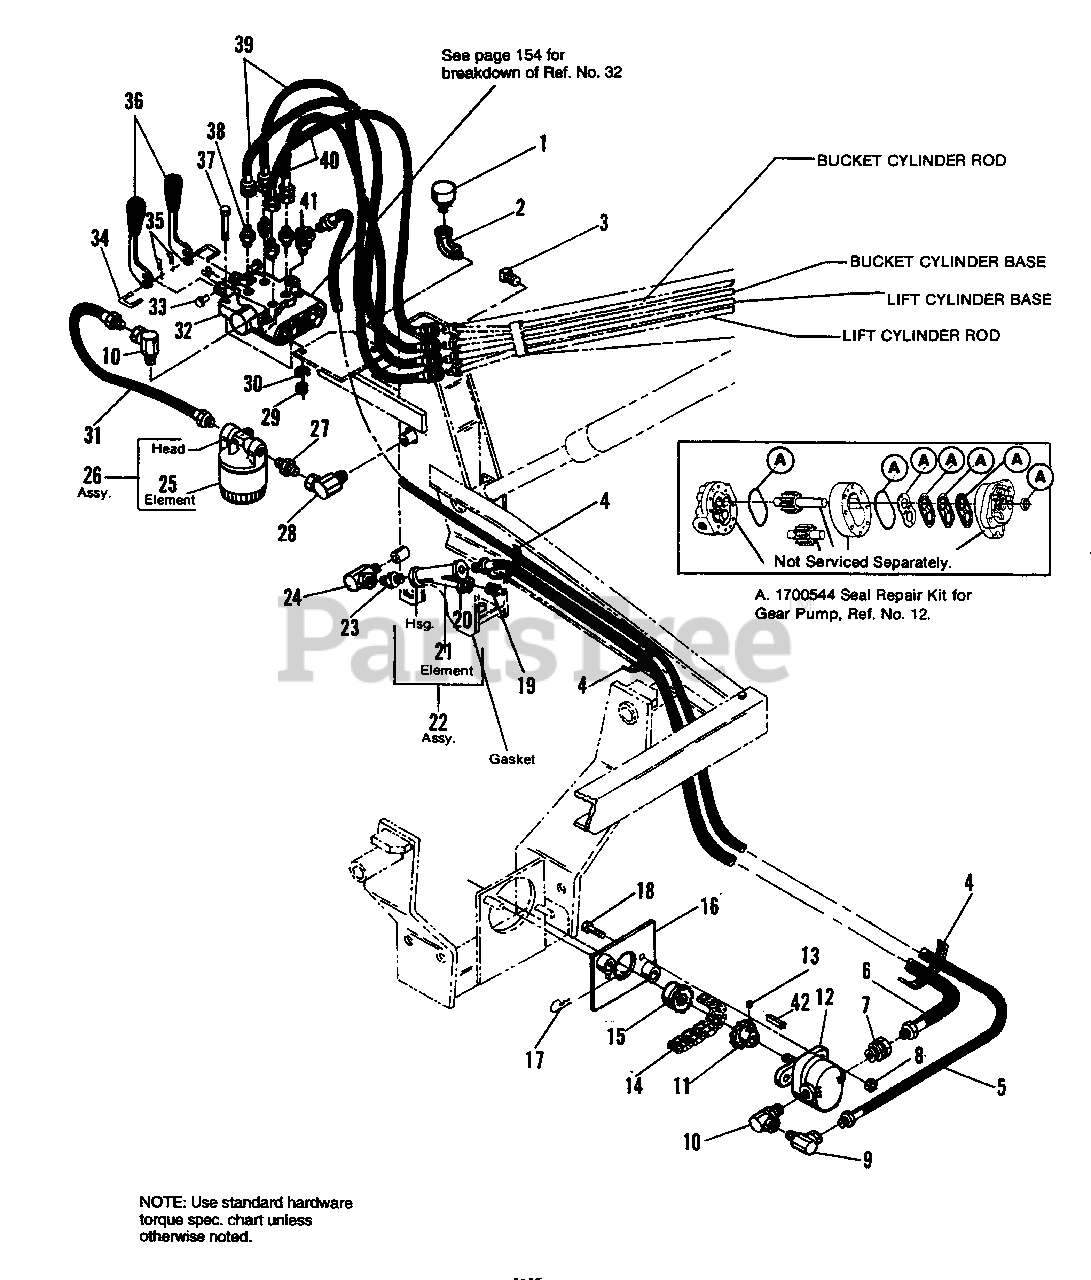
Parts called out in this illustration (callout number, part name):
1	CAP, Breather
2	FITTING, Street Elbow, 1/2 x 90ø
3	PLUG, Pipe, 1/2
4	STRAP, Adjustable Tie, 3/16 x 14-3/16
5	HOSE, 3/8 x 72"
6	HOSE, 1/2 x 48"
7	FITTING, Adaptor Union, 7/8-1/2
8	LOCKNUT, 3/8-16
9	FITTING, Elbow Adaptor, 3/8-3/8 x 90ø
10	FITTING, Elbow Adaptor, 3/4-3/8 x 90ø
11	SPROCKET, w/Keyway Hub, #40B12
12	GEAR PUMP
13	SETSCREW, Skt. Hd., 1/2-20 x 1/4
14	CHAIN, Roller, #40-2 x 12
15	SPROCKET, w/Spline Hub, #40B12
16	BRACKET, Pump Mounting
17	Pin, Hair Cotter, 3/32 x 1-7/8
18	CAPSCREW, 3/8-16 x 1-1/4
19	PLUG, Pipe, 3/8
20	GASKET
21	SCREEN, Replacement
23	FITTING, Adaptor, 1/2-1/2
24	FITTING, Elbow Adaptor, 1/2-1/2 x 90ø
25	ELEMENT, Filter,10 Micron
26	FILTER ASSY., w/ Element
27	FITTING, Adaptor, 3/8-3/8
28	FITTING, Elbow Adaptor, 1/2-3/8 x 90ø
29	NUT, Hex, 1/4-20
30	LOCKWASHER, 1/4
31	HOSE, 3/8 x 14"
32	VALVE ASSY.
33	PIN, 1/4 x 3/4
35	PIN, Cotter
36	HANDLE, Valve
37	CAPSCREW, 1/2-20 x 2-1/4
38	FITTING, Adaptor, 9/16-9/16
39	HOSE, 1/4 x 22-1/2
40	HOSE, 1/4 x 20"
41	FITTING, Adaptor Union, 3/4 x 3/8 x 45ø
42	KEY, Woodruff, #5, 1/8 x 5/8
A	SEAL REPAIR KIT
